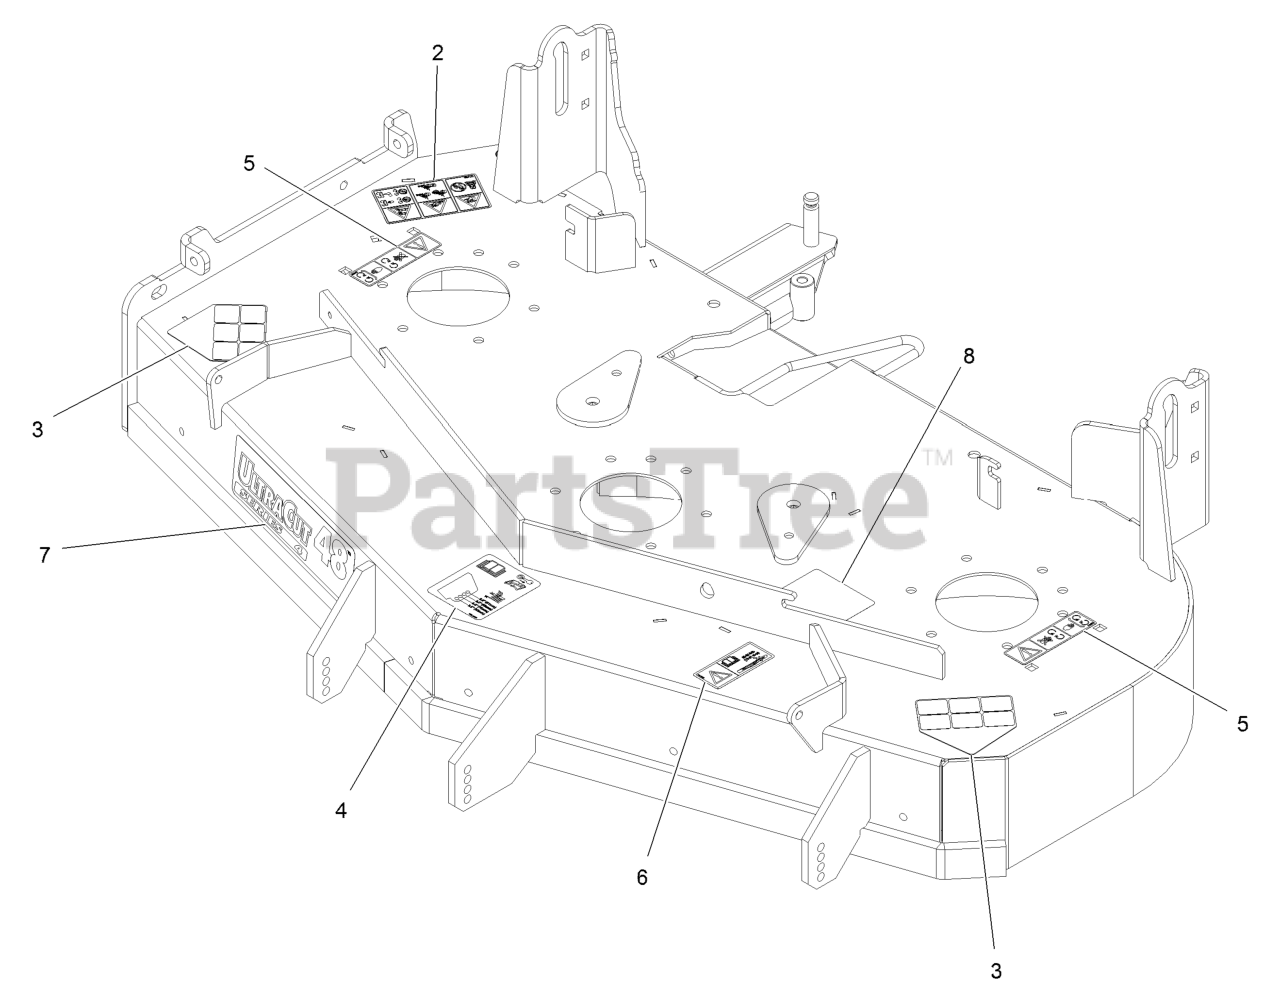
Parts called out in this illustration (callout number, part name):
2	DECAL-DANGER
3	DECAL-DANGER
4	DECAL-ROLLER, ANTI-SCALP
5	DECAL-COVER, MISSING
6	DECAL-BOLT TORQUE
7	DECAL,ULTRACUT 48 SERIES
8	DECAL-BELT ROUTING
